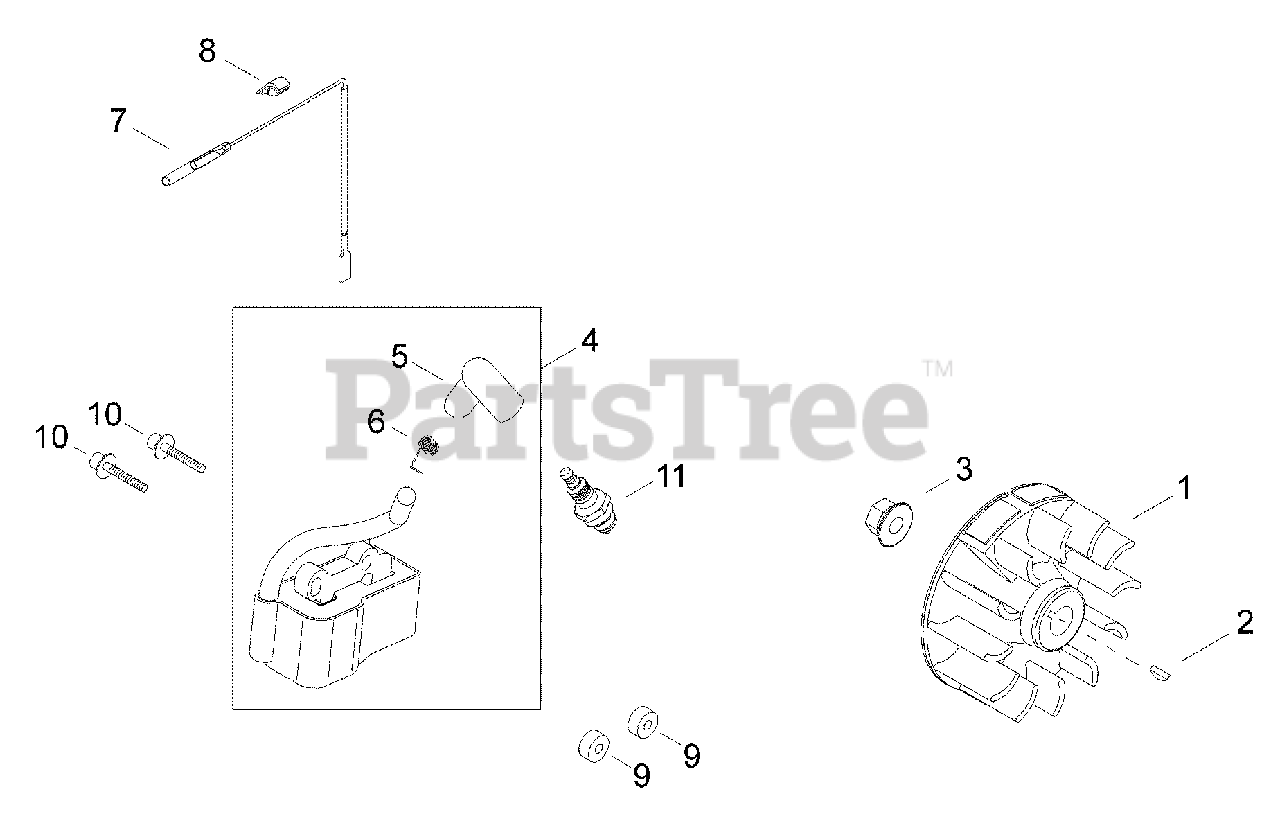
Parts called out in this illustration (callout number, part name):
1	FLYWHEEL
2	KEY, WOODRUFF 3×10
3	NUT M8
4	COIL ASSY, IGNITION
5	CAP, SPARK PLUG
6	TERMINAL, SPARK PLUG
7	LEAD - IGNITION
8	GROMMET, LEAD
9	INSULATOR 4.2×11×6
10	BOLT M4×26
11	SPARK PLUG - CMR5H
